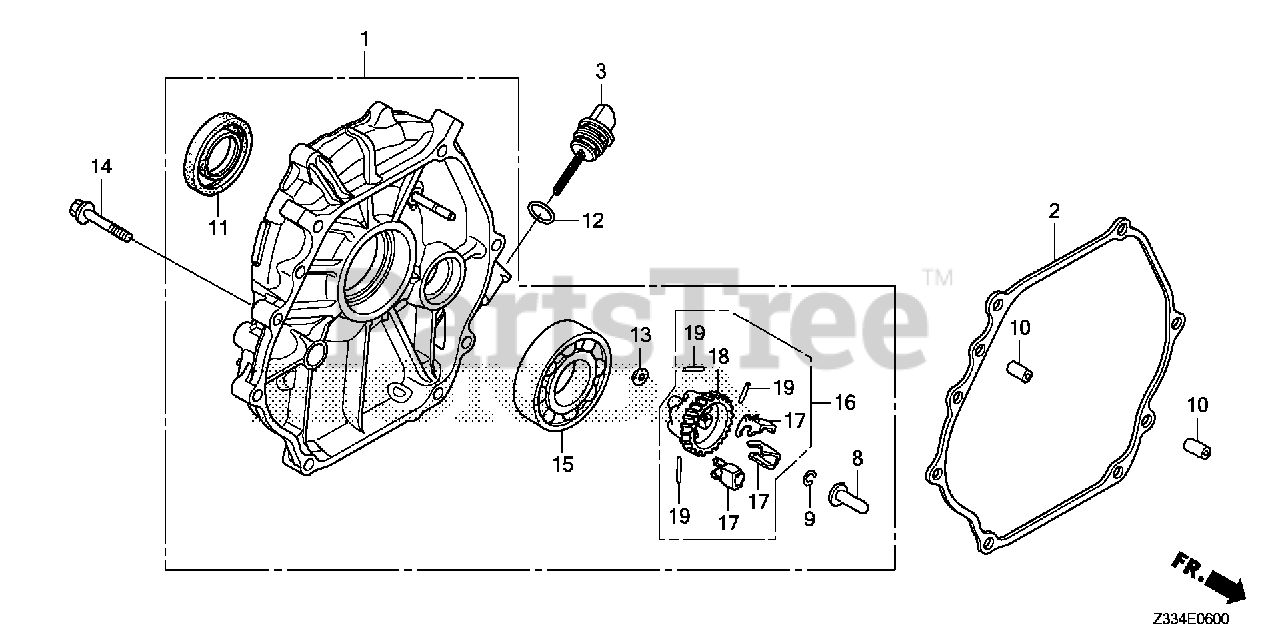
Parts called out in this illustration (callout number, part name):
1	COVER ASSY., CRANKCASE
2	GASKET, CASE COVER
3	CAP, OIL FILLER
8	SLIDER, GOVERNOR
9	CLIP, GOVERNOR HOLDER
10	PIN, DOWEL (8X12)
11	OIL SEAL (30X46X8) (NOK ASIA)
12	O-RING (26X2.7)
13	WASHER, PLAIN (6MM)
14	BOLT, FLANGE (8X35)
15	BEARING, RADIAL BALL (6206)
16	GOVERNOR ASSY.
17	WEIGHT, GOVERNOR
18	HOLDER, GOVERNOR WEIGHT
19	PIN, GOVERNOR WEIGHT
